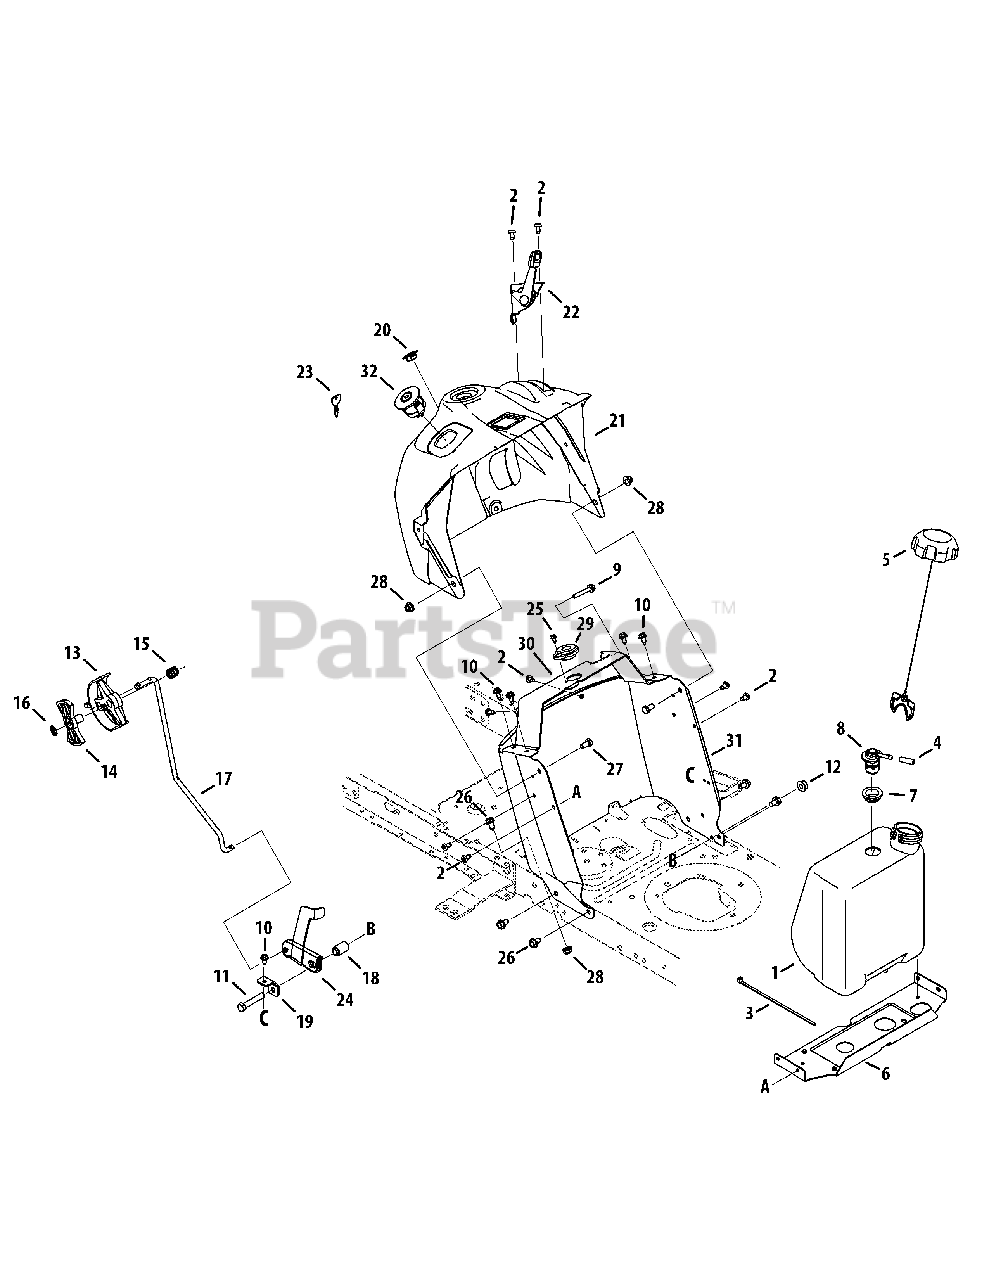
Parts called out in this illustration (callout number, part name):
1	Fuel Tank, 1.36 Gal.
2	Screw, Tap, 1/4-20, 0.500
3	Cable Tie, 36.0 Long
4	Hose Vent
5	Fuel Cap, 2.25"
7	Rubber Grommet, 23 x 3.55
8	Rollover Valve
9	Hex Screw, 1/4-20 x 1.50
10	Tap Screw, 1/4-20, 0.625
11	Hex Screw, 3/8-16, 2.00, Gr5, Std
12	Flange Lock Nut, 3/8-16
13	Shift Lever
14	Index Control
15	Compr. Spring, .685 OD x .63
16	Lock Washer, 1/4
17	Speed Selector Control Rod
18	Flange Spacer, .390 X .671 X 1.095
19	Speed Latch
20	Choke Plug
21	Dash, Upper
22	Throttle/Choke Cable Assembly
24	Speed Latch - No RMC
25	Screw, #10-16 x .500
26	Tap Screw,5/16-18, 0.625
27	Hex Screw, 5/16-18 x .625
28	Flange Lock Nut, 5/16-18
29	Bearing, .628 ID x 1.36
30	Bracket, Steering Support
31	Dash, Lower
32	Key Switch
